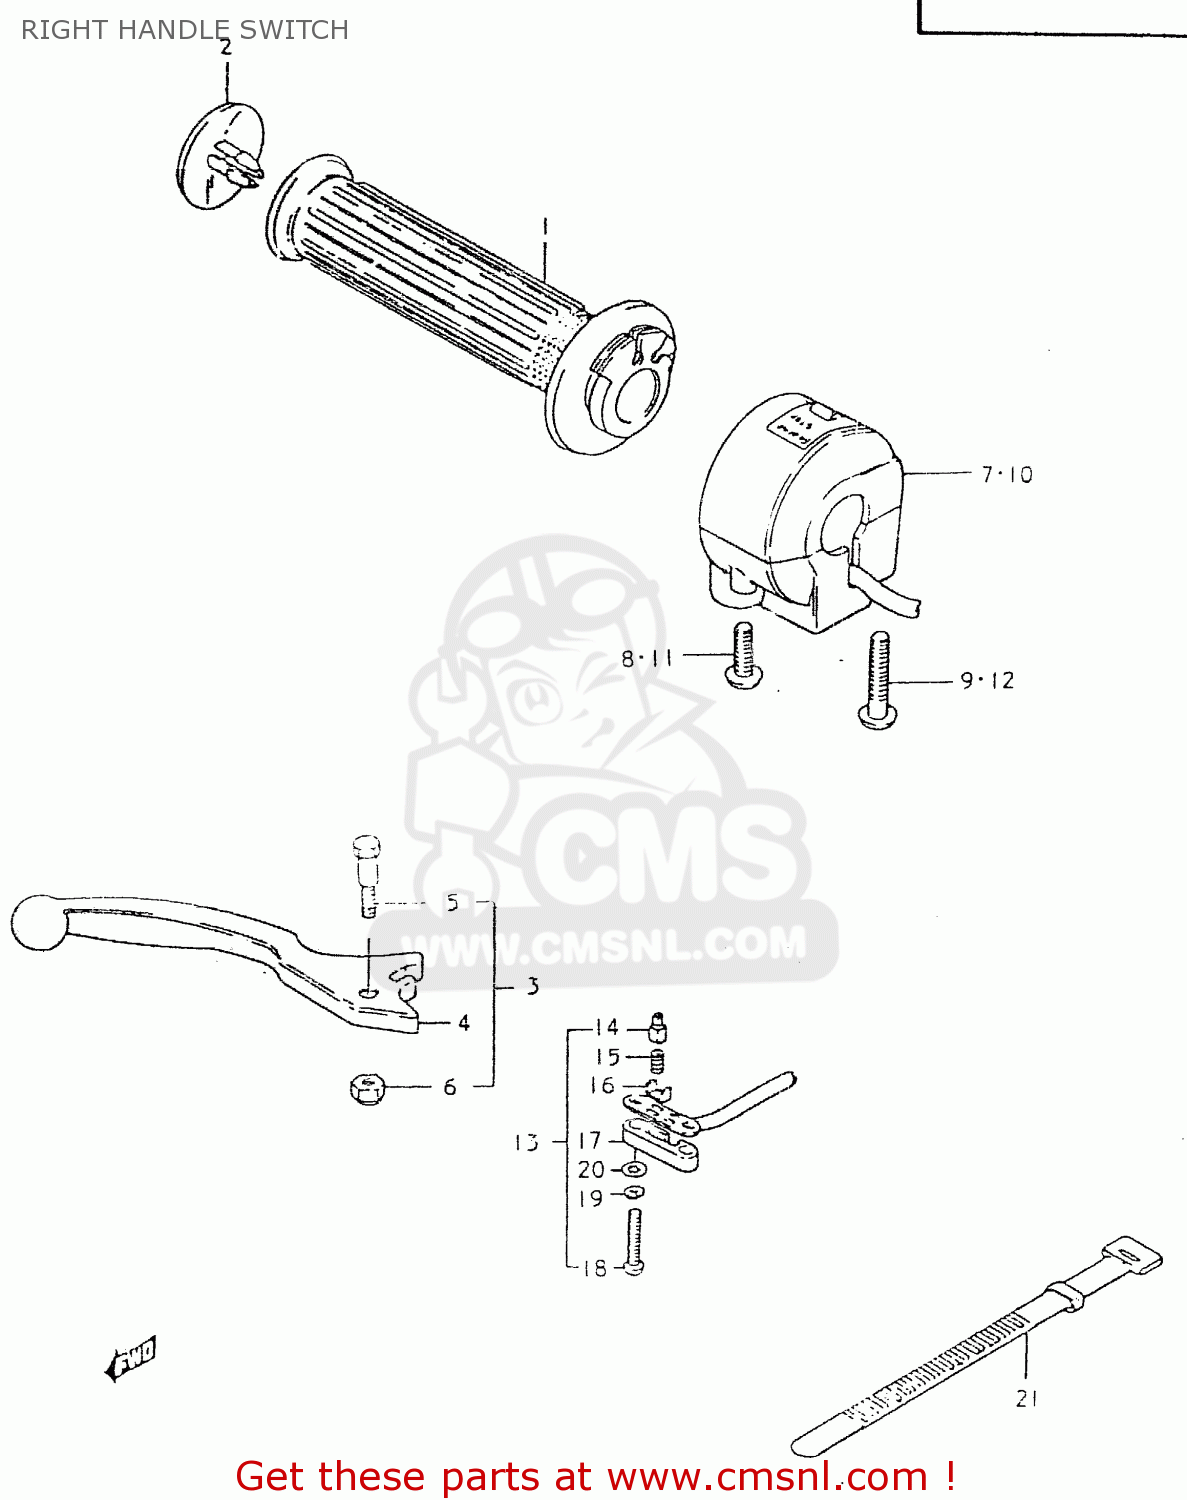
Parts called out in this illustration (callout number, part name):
1	GRIP,THROTTLE
2	CAP,GRIP END
3	LEVER ASSEMBLY,BRAKE
4	LEVER,BRAKE
5	BOLT
6	NUT 6MM
7	SWITCH ASSEMBLY,HANDLE,RIGHT
8	SCREW
9	SCREW
10	SWITCH ASSY, HANDLE RH
11	SCREW
12	SCREW
13	SWITCH ASSEMBLY
14	HOLDER
15	SPRING
16	PLATE
17	COVER,FR BK TERMINAL BASE
18	SCREW
19	LOCK WASHER
20	WASHER
21	CLAMP(L:120)
